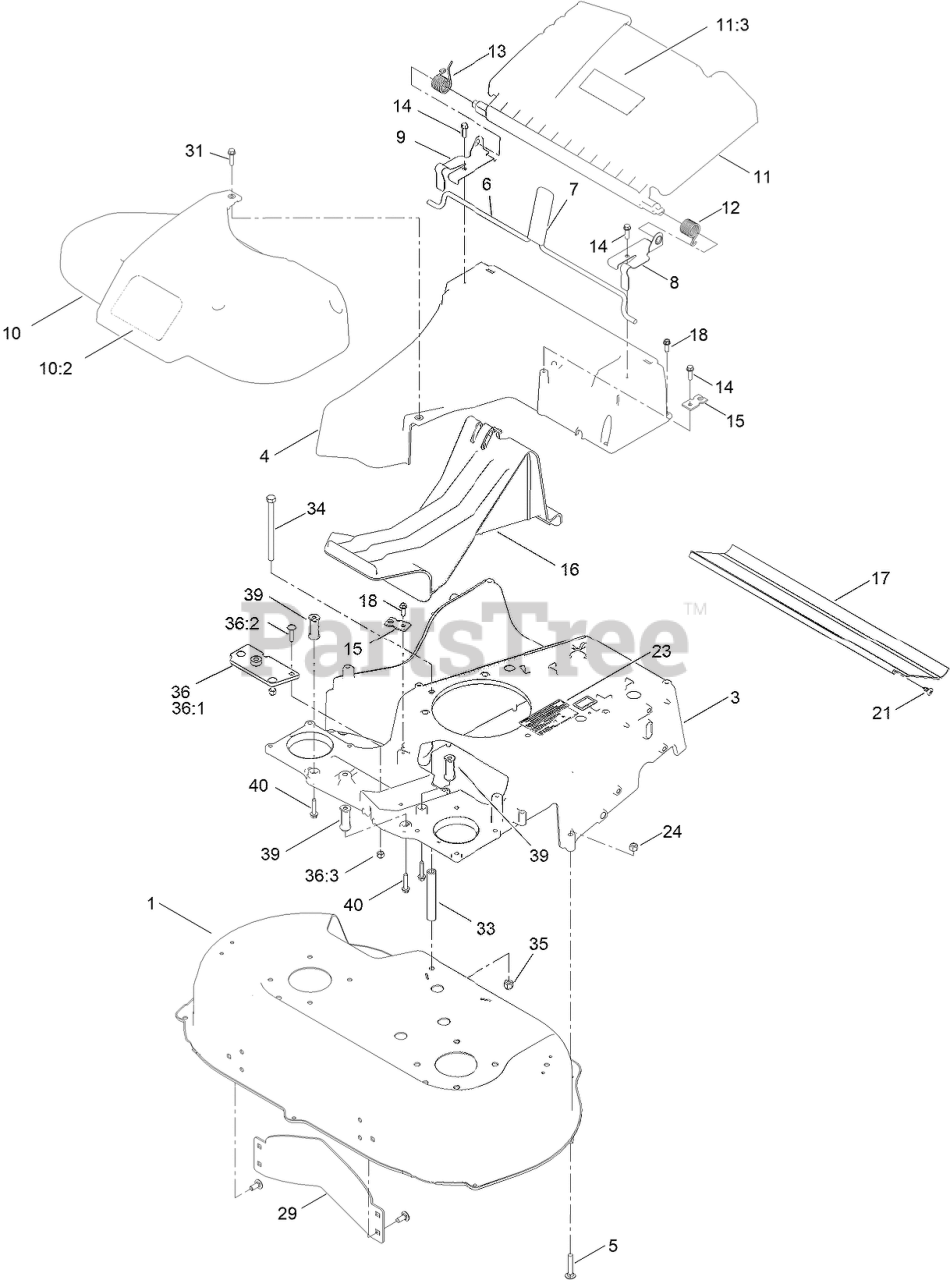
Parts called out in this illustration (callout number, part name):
1	HOUSING ASM
3	FRAME-30"
5	BOLT-CAR
6	ROD-RELEASE, HANDLE
7	GRIP-LEVER
8	BRACKET-DOOR, LH
9	BRACKET-DOOR, RH
10	BELT COVER ASM
10:2	DECAL-COVER, BELT
11	REAR DEFLECTOR ASM
11:3	DECAL-WARNING
12	SPRING-TORSION
13	SPRING-TORSION
14	SCREW-HWH
15	BRACKET-CABLE, TRACTION
16	PLUG-MULCH
17	SHIELD-TRAILING
18	SCREW-HWHTF
21	SCREW-PTH
23	DECAL-ARRESTOR, SPARK
24	NUT-LOCK, NI
29	BAFFLE-CONTROL
31	SCREW-HWHTF
33	SPACER-SHIELD
34	SCREW-HH
35	NUT-HEX
36	FRAME PLATE KIT
36:1	PLATE-FRAME
36:2	SCREW-CARR
36:3	NUT-LOCK, NI
39	SPACER-FRAME, 30 IN.
40	SCREW-HWHTF
